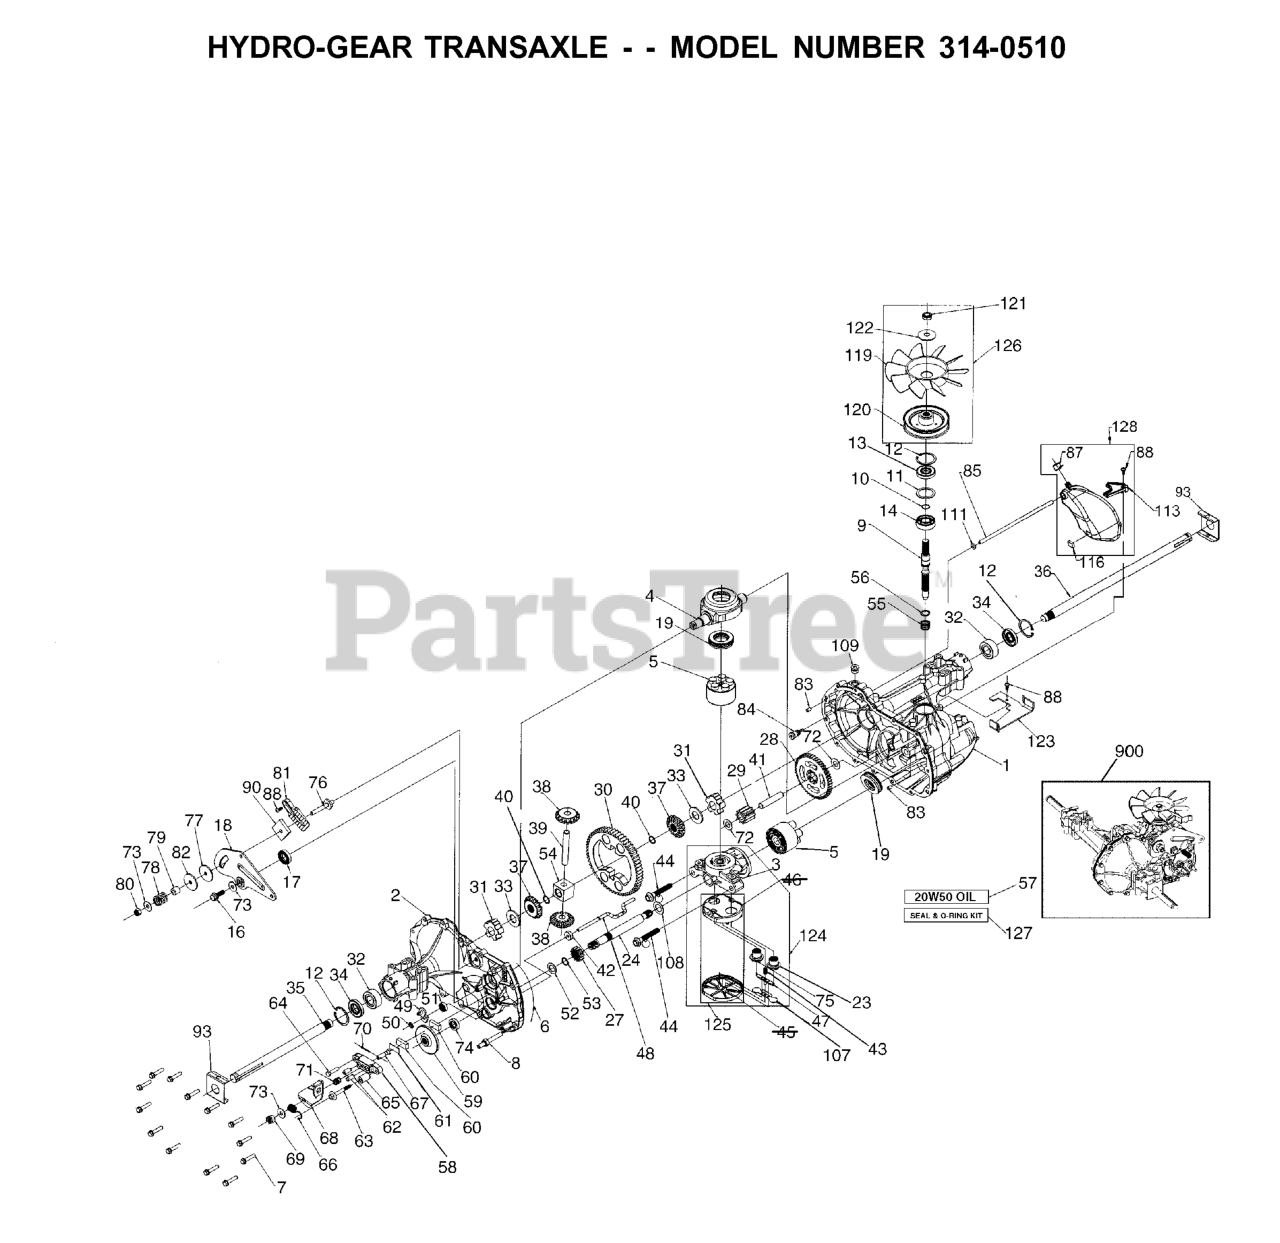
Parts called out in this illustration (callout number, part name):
5	KIT CYLINDER #70331
14	BEARING.BALL(50315)
19	BEARING, THRUST 50551
33	WASHER.HYDRO-GEAR 44875
39	SHAFT.50146
55	SPRING 2003014
60	BRAKE PUCK (44132)
61	PUCK PLATE 44134
62	BRAKE PIN 44127
64	BOLT W/NYLOCK 44433
73	WASHER .34X.88X.06.44130
78	SPRING HELICAL COMP 50277
79	SPACER.HYDRO GEAR 50278
80	LOCKNUT, HEX 5/16-24
87	CAP, VENT ASSY
